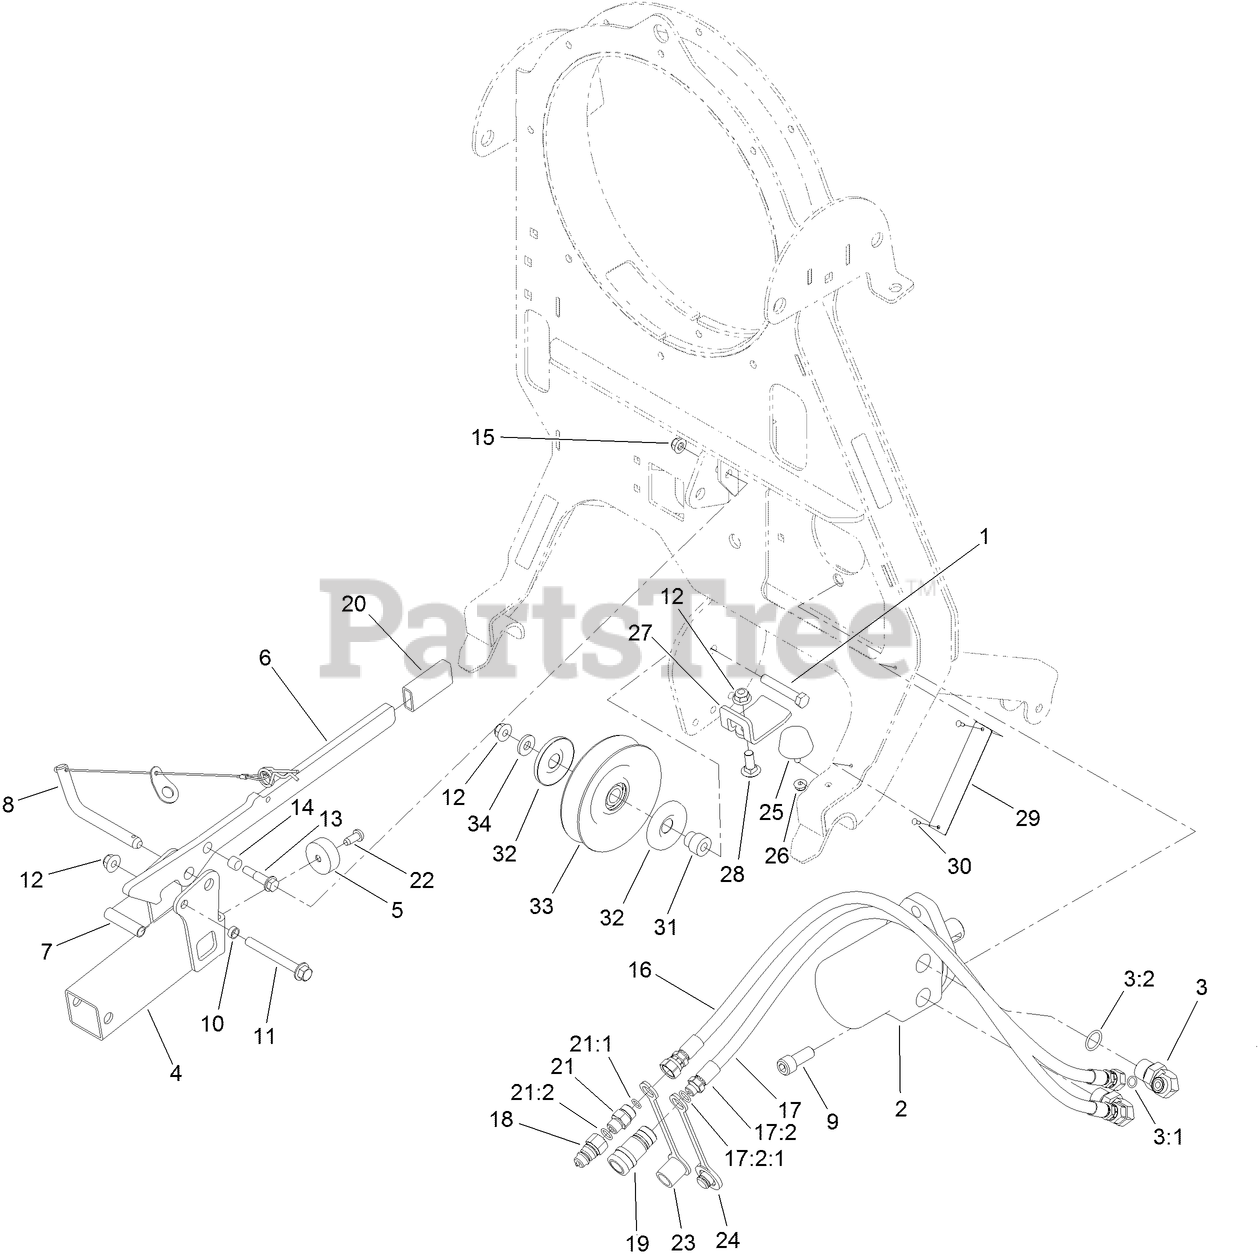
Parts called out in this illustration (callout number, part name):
1	SCREW-HH
2	HYD MOTOR ASM
3	FITTING-ELBOW 90
3:1	O-RING
3:2	O-RING
4	BLOWER HITCH ASM
5	BUMPER-RUBBER
6	HANDLE-LATCH
7	SPACER-ROLLER
8	PIN-ROPS W/ LANYARD
9	SCREW-HSH
10	SPACER
11	SCREW-HHF
12	NUT-HF, NI
13	SCREW-SHOULDER
14	BUSHING
15	NUT-HF, NI
16	HOSE ASM
17	HOSE ASM
17:2	FITTING-STRAIGHT, RIGID
17:2:1	O-RING
18	NIPPLE-DISCONNECT, QUICK
19	COUPLER-DISCONNECT, QUICK
20	GRIP-FLAT
21	FITTING-STRAIGHT
21:1	O-RING
21:2	O-RING
22	SCREW-BHTF
23	CAP-DUST
24	PLUG-DUST
25	BUMPER
26	NUT-HF
27	BRACKET-STOP
28	SCREW-HH
29	PLATE-SERIAL
30	RIVET-POP
31	BUSHING-IDLER
32	SHIELD-GUARD, DUST
33	PULLEY-IDLER
34	WASHER-SPACER
